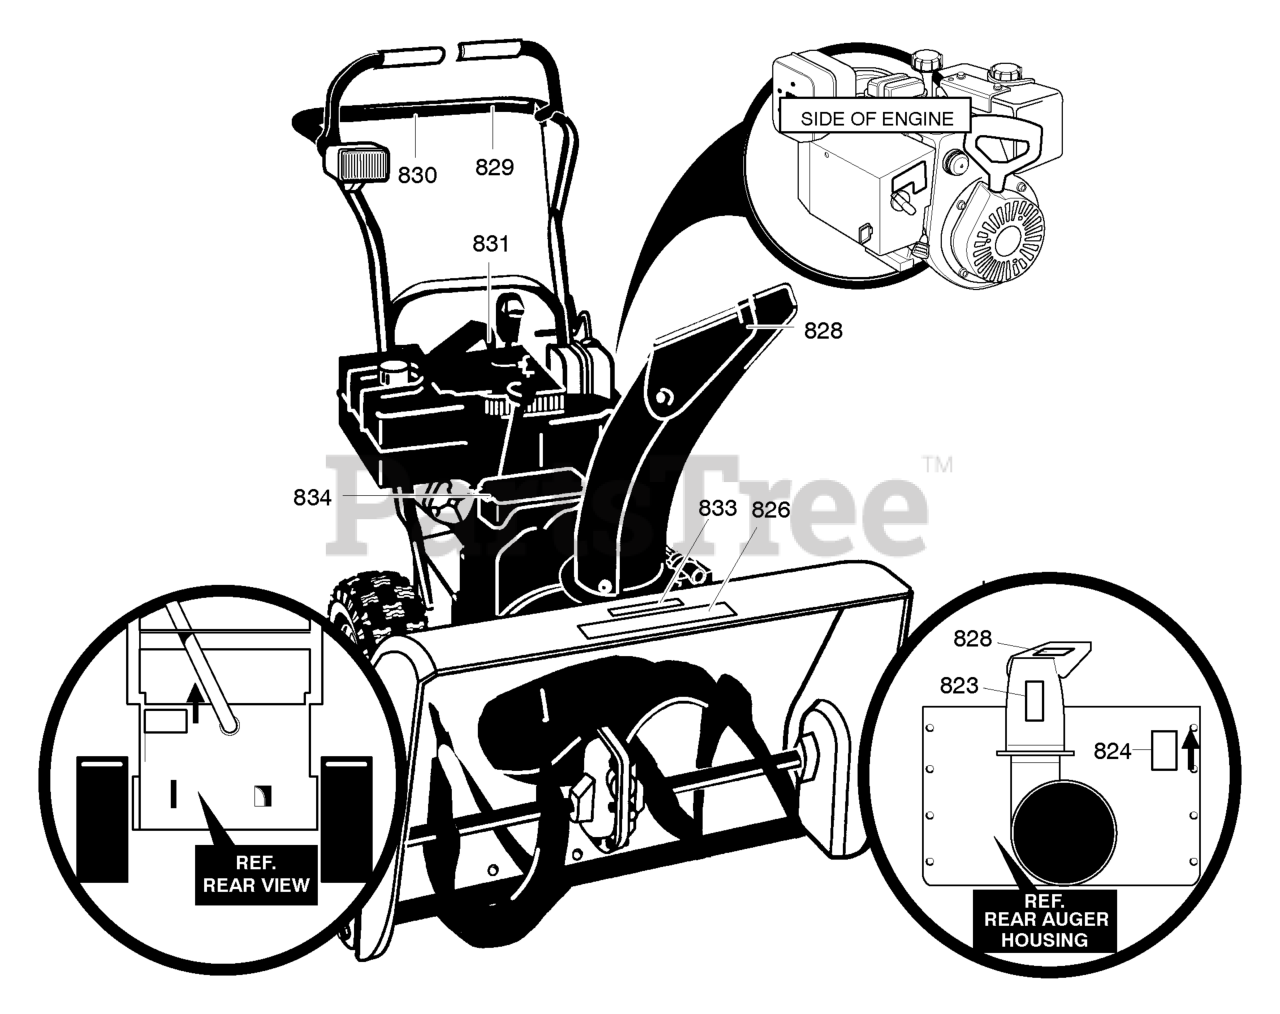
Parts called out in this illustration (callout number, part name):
823	DECAL, DANGER CHUTE HAND
824	DECAL, DANGER FOOT
826	DECAL, 9/24
828	DECAL, THROWN OBJECTS
829	DECAL, DRIVE CLUTCH
830	DECAL, AUGER CLUTCH
831	DECAL, GEAR SELECTOR
833	DECAL, CLEAN & CLEAR BRUSH
834	DECAL, TOOLBOX INFORMATION
